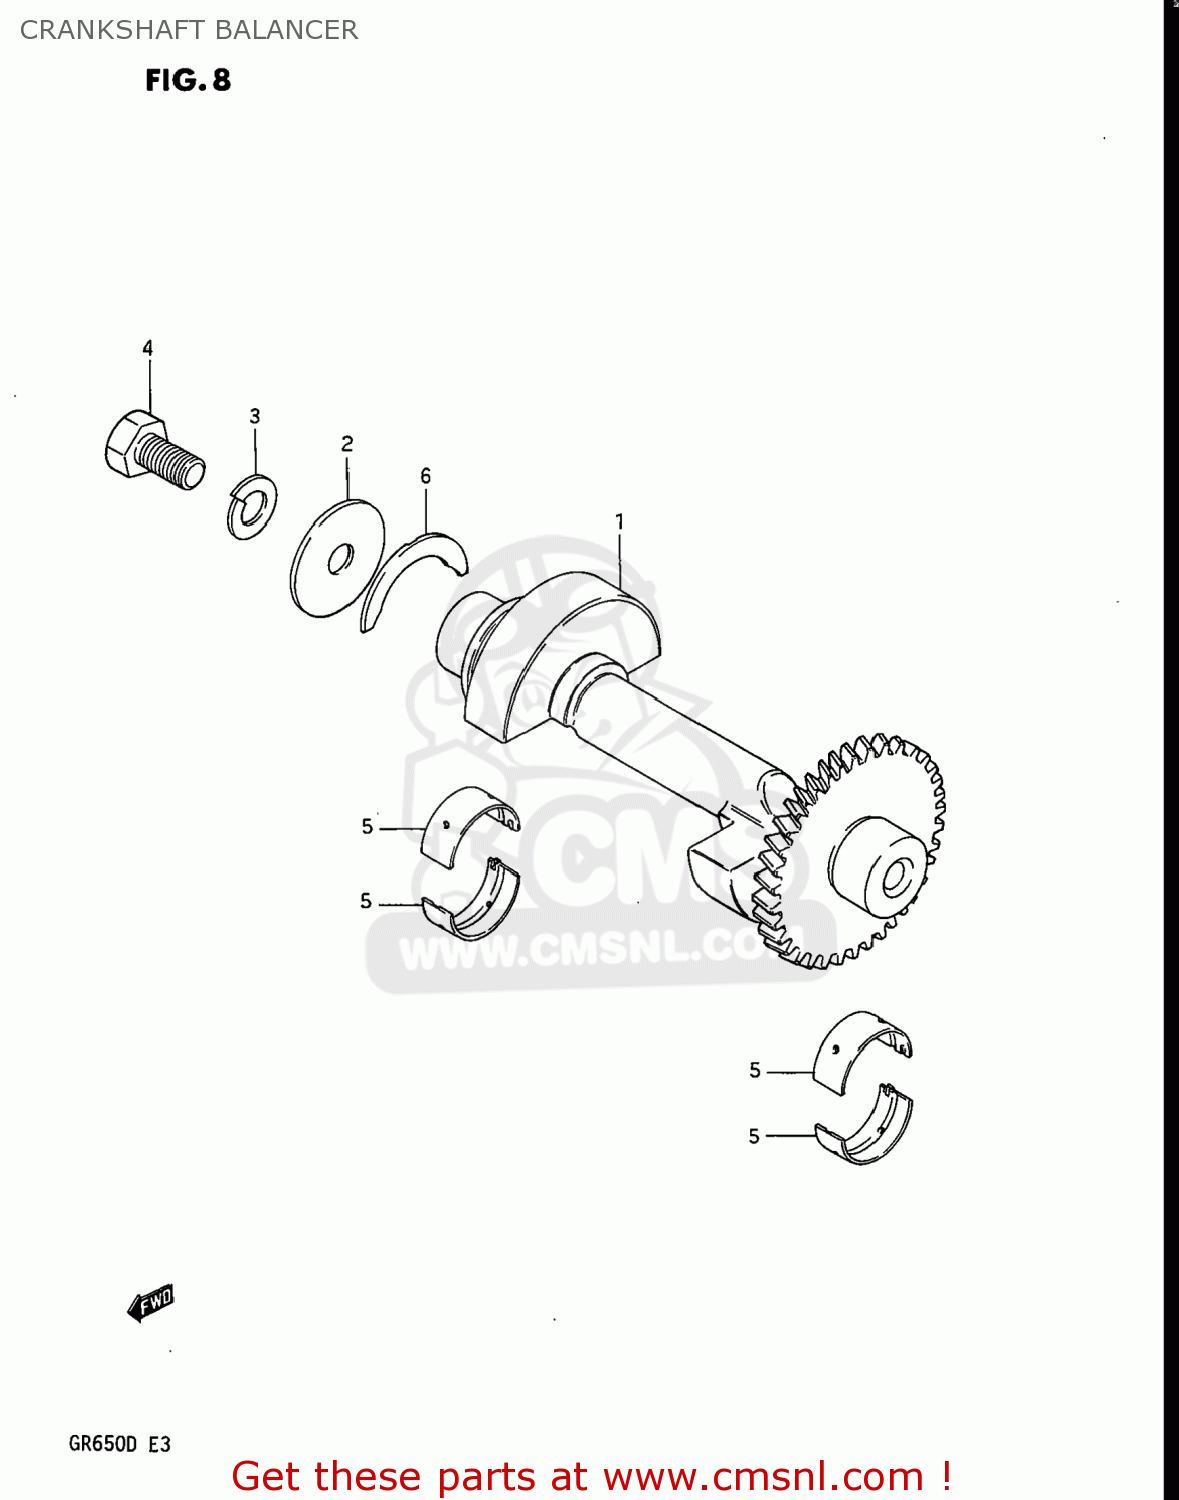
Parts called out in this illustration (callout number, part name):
1	BALANCER,CRANKSHAFT
2	WASHER
3	WASHER,LOCK 12
4	BOLT
5	METAL CRANKSHAFT (BROWN)
6	PLATE,CRANK THRUST
